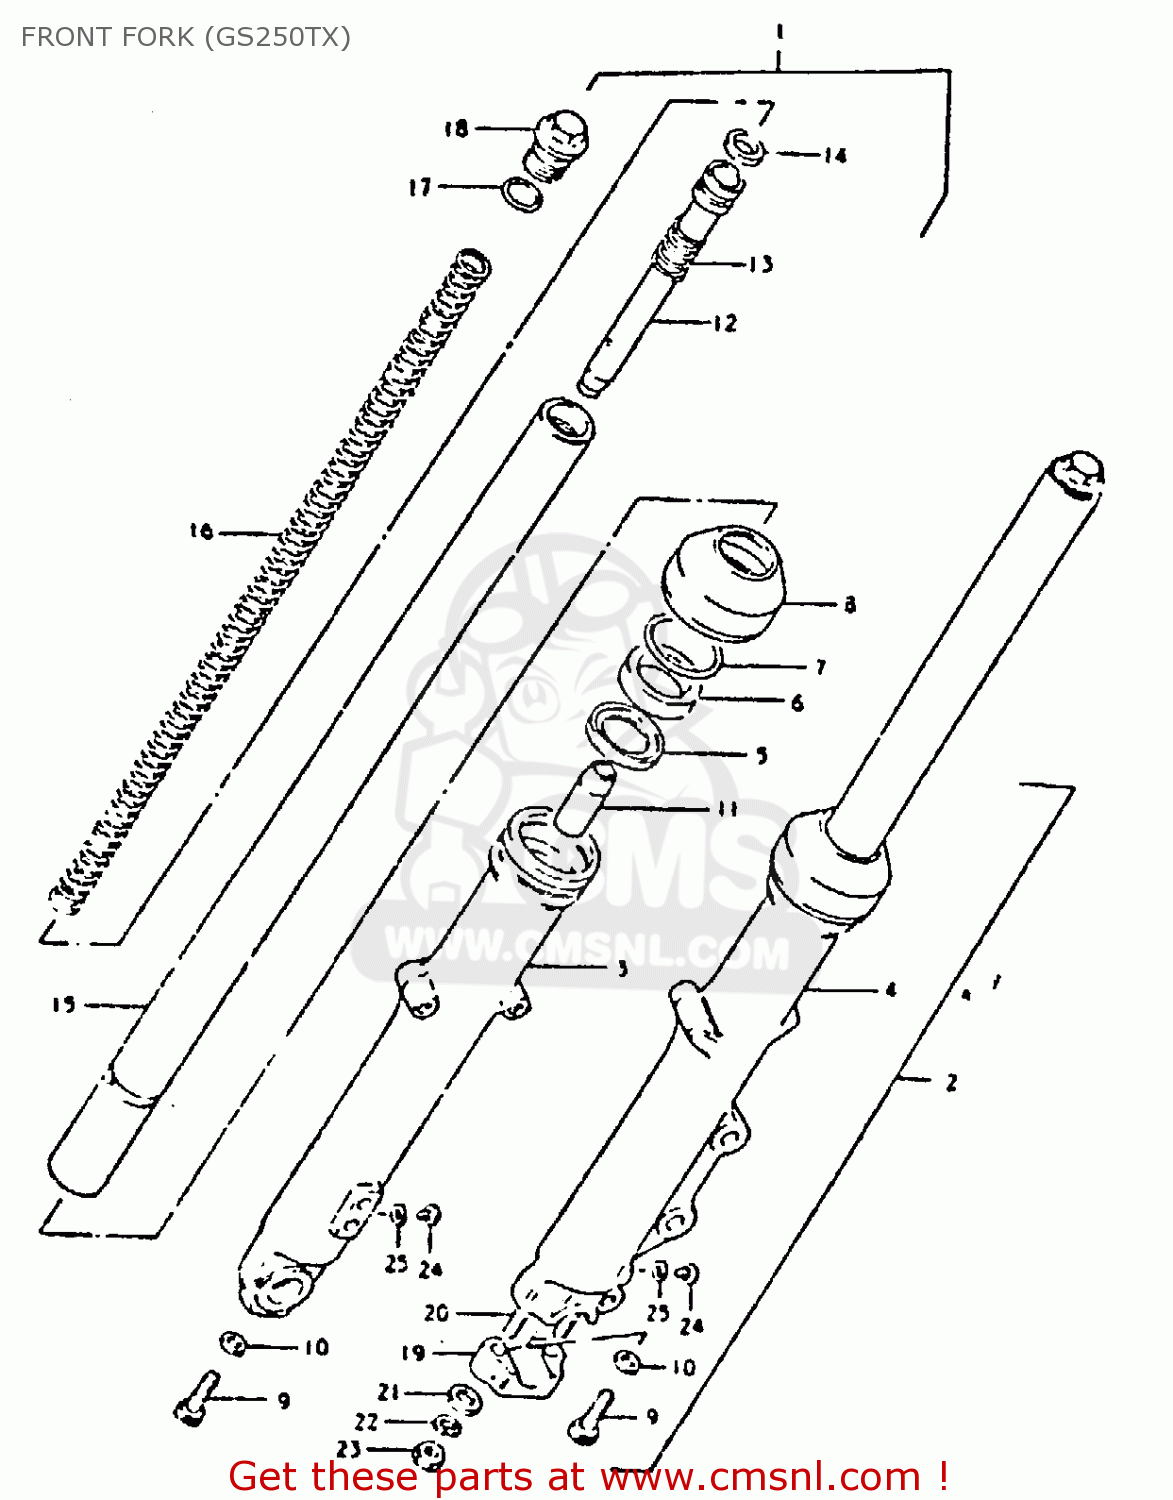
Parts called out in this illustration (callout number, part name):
1	DAMPER ASSEMBLY,FRONT FORK,RIGHT
2	DAMPER ASSEMBLY,FRONT FORK,LEFT
3	TUBE,FORK,OUTER,RIGHT
4	TUBE,FORK,LEFT,OUTER
5	SPACER,OIL SEAL
6	OIL SEAL,FRONT FORK
7	CIRCLIP,FORK OIL SEAL
8	BOOT
9	BOLT(8X27)
10	GASKET (NAS)
11	PIECE,OIL LOCK
12	CYLINDER,FRONT FORK
13	SPRING,REBOUND
14	RING,PISTON
15	TUBE,INNER
16	SPRING
17	O RING
18	BOLT
19	HOLDER,AXLE
20	STUD 8X25
21	WASHER
22	LOCK WASHER
23	NUT (8MM)
24	SCREW 4X6
25	GASKET (NAS)
